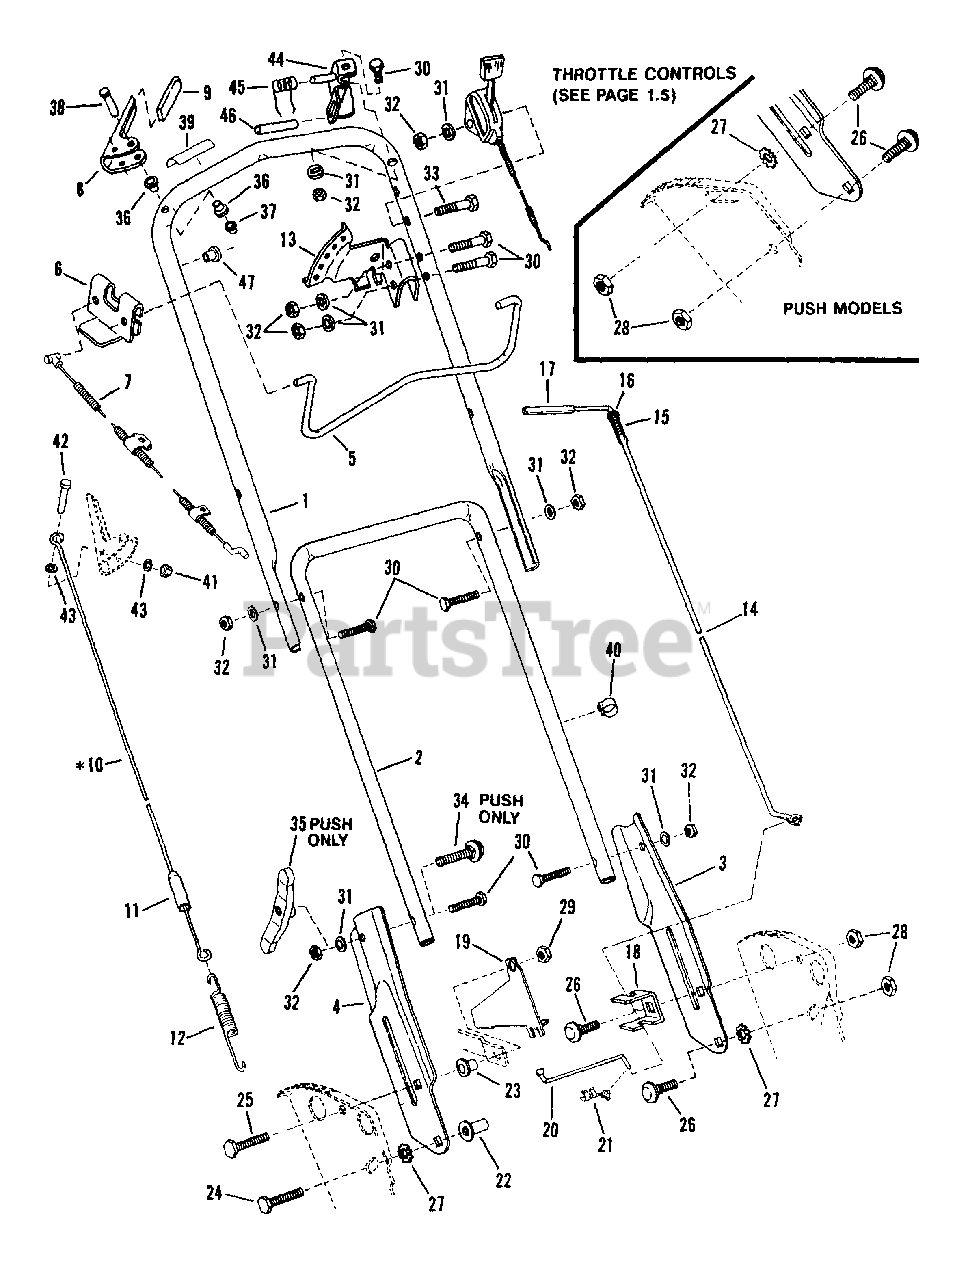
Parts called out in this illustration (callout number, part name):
1	HANDLE, Upper
2	HANDLE, Middle
3	HANDLE, Lower L.H.
4	HANDLE, Lower R.H.
5	CONTROL, Blade
6	CLIP, Blade Control
7	CABLE, Clutch Control
8	HANDLE, Wheel Drive
9	GRIP, Handle
10	CABLE, Clutch Pull
11	COVER, Vinyl
12	SPRING, Clutch
13	SECTOR, Speed
14	LEVER, Speed Control
15	SPRING, Speed Control
16	WASHER, 3/8" Flat
17	GRIP, Speed Contr. Handle
18	ANCHOR, Speed Control
19	GUIDE, Lower(V-Belt)
20	ROD, Transfer
21	CLIP, Transfer Rod
22	TEE-NUT, 5/16-18
23	BUSHING, Differential
24	BOLT, 5/16-18x1" Hex Flange Lock
25	CAPSCREW, 5/16-24x1
26	BOLT,5/16 x 18 x 5/8 Carr.
27	LOCKWASHER, 5/16 I.E.Tooth
28	NUT, 5/16-18 Hex Flange Lock
29	NUT, 5/16-24 Center Lock
30	CAPSCREW, 1/4-28 x 1-3/8
31	LOCKWASHER, 1/4 Int.Tooth
32	NUT, 1/4-28 Hex
33	CAPSCREW,.1/4-28 x 1-3/4
34	BOLT, 1/4-20x1-7/8" Carriage
35	WING-NUT, 1/4-20
36	BUSHING
37	PUSH-NUT
38	PIN, Clutch Handle
39	DECAL, Starting Procedure
40	CLIP, Cable/Wiring
41	PUSH-NUT
42	PIN, 3/16 x 1-3/4" Clevis
43	WASHER, #10 Flat
44	ASSEMBLY, Blade Control Bracket
45	SPRING, Blade Control
46	GRIP, Pivot
47	BUSHING
